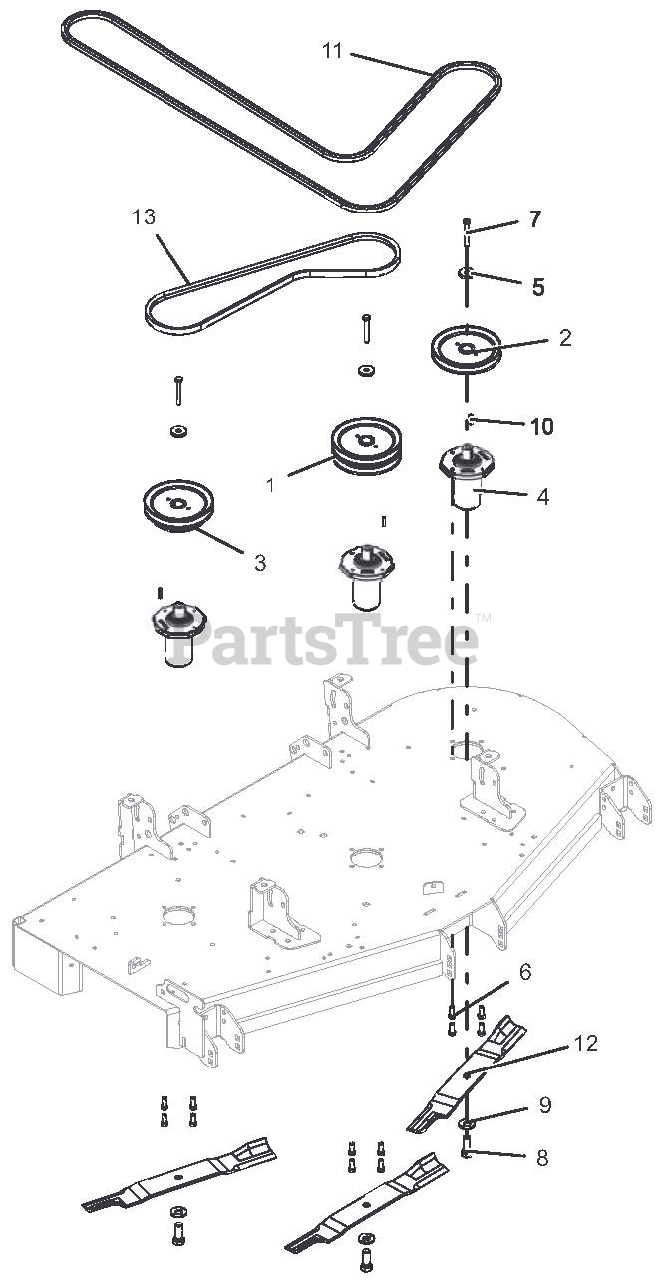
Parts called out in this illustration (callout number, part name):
1	PULLEY, DOUBLE 1"ID X 6.75"OD-BLACK
2	PULLEY, V-1" ID X 6.75" OD-BLACK
3	PULLEY, DOUBLE -1" ID X 6.75" & 5.25" OD
4	SERVICE, ASM SPINDLE- DUCTILE
5	RETAINER, SHEAVE SPINDLE
6	BLT-HEX .38-16X1.00 GR5 YWZC EP30
7	BLT-HEX .38-16X2.75 GR8 YWZC
8	BLT, HEX .62-18X1.75 GR8 YWZC
9	WSHR, BLVL .63X1.625X.14
10	KEY-SQ .250X.250X1.00 RC 40-50
11	BELT, BB 118.00 WRAPPED HEX
12	BLADE, MOWER 60"
13	BELT, B 63.00 RAW COGGED
